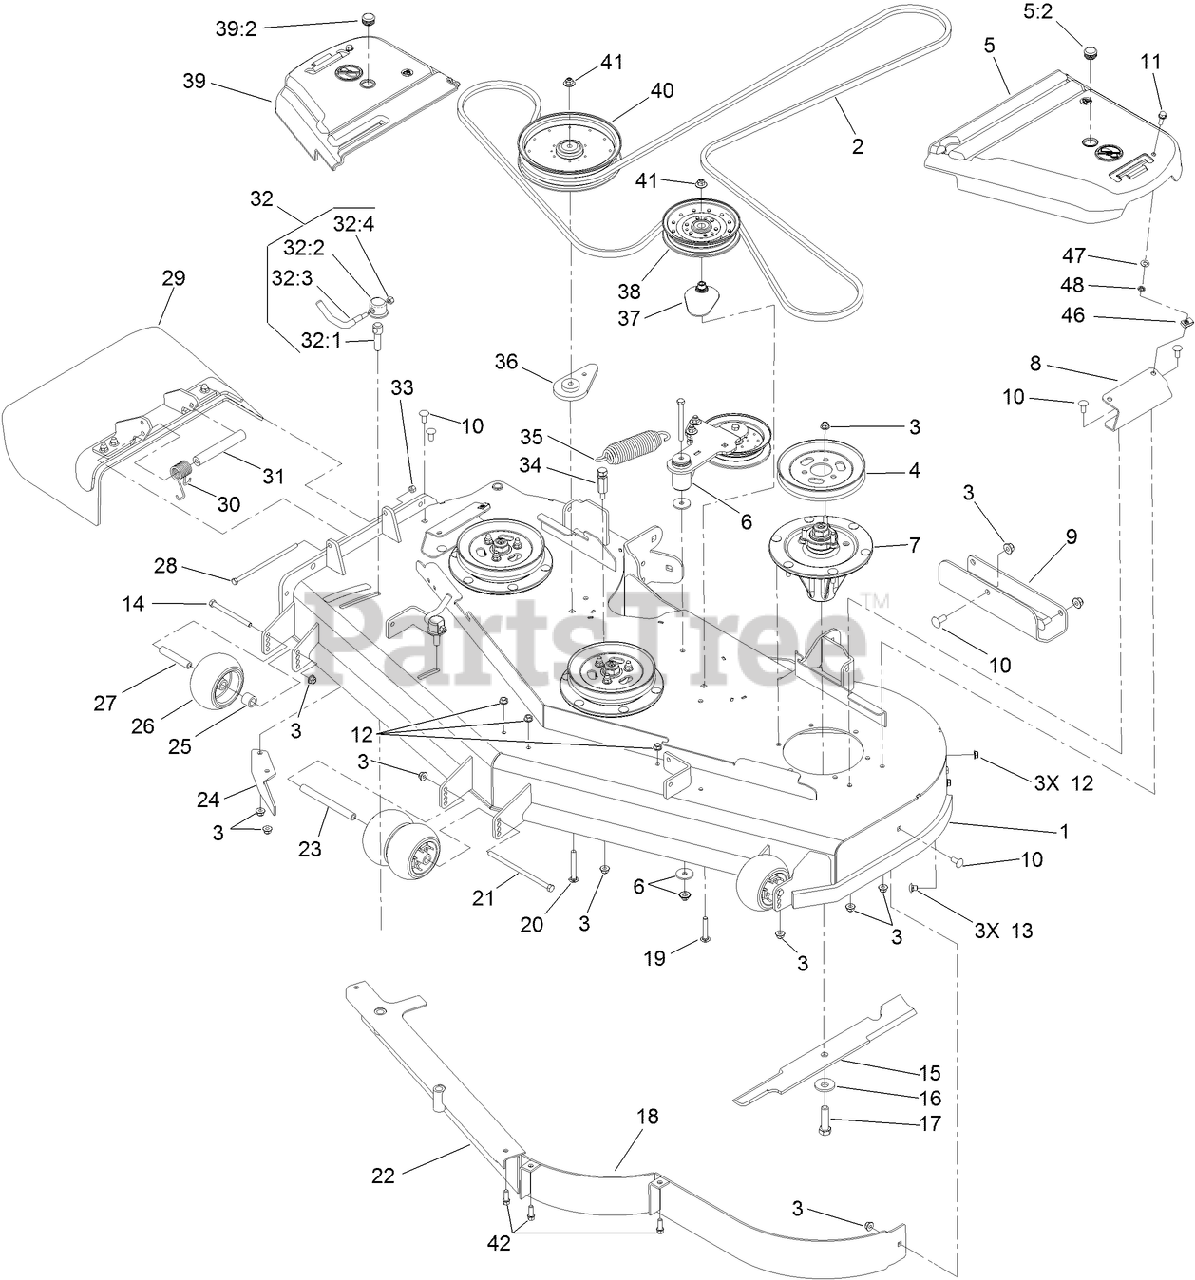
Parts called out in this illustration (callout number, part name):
1	DECK DECAL ASM
2	BELT-V
3	NUT-HF, NI
4	Pulley
5	LH BELT COVER ASM
5:2	PLUG-PLASTIC
6	IDLER ARM ASM
7	SPINDLE ASM
8	BRACKET-COVER, BELT
9	PLATE-SKID
10	SCREW-CARR
11	SCREW-HHF
12	NUT-HHF, WHIZ
13	SCREW-CARR
14	SCREW-HH
15	BLADE-HI FLOW
16	Washer-Blade Bolt, Heavy
17	SCREW-BLADE
19	BOLT-CARR, SHORT NECK
20	SCREW-CARR
21	SCREW-HH
23	SPACER-WHEEL
24	BAFFLE-DISCHARGE
25	TUBE-SPACER
26	ROLLER-SCALP, ANTI
27	TUBE-SPANNER
28	SCREW-HH
29	RUBBER DEFLECTOR ASM
30	SPRING-TORSION
31	SPACER
32	LEVER ASM
32:1	Screw-Lock
32:2	CAP-LOCK
32:3	Lever-Lock
32:4	NUT-LOCK, NI
33	NUT-LOCK, NI
34	ANCHOR-SPRING, TALL
35	SPRING-EXTENSION
36	SPACER-IDLER
37	SPACER-PULLEY
38	PULLEY-IDLER, FLAT
39	RH BELT COVER ASM
39:2	PLUG-PLASTIC
40	PULLEY-IDLER
41	NUT-FLANGE, NI
42	SCREW-HWH
46	NUT-U
47	WASHER-THRUST
48	NUT-PUSH
